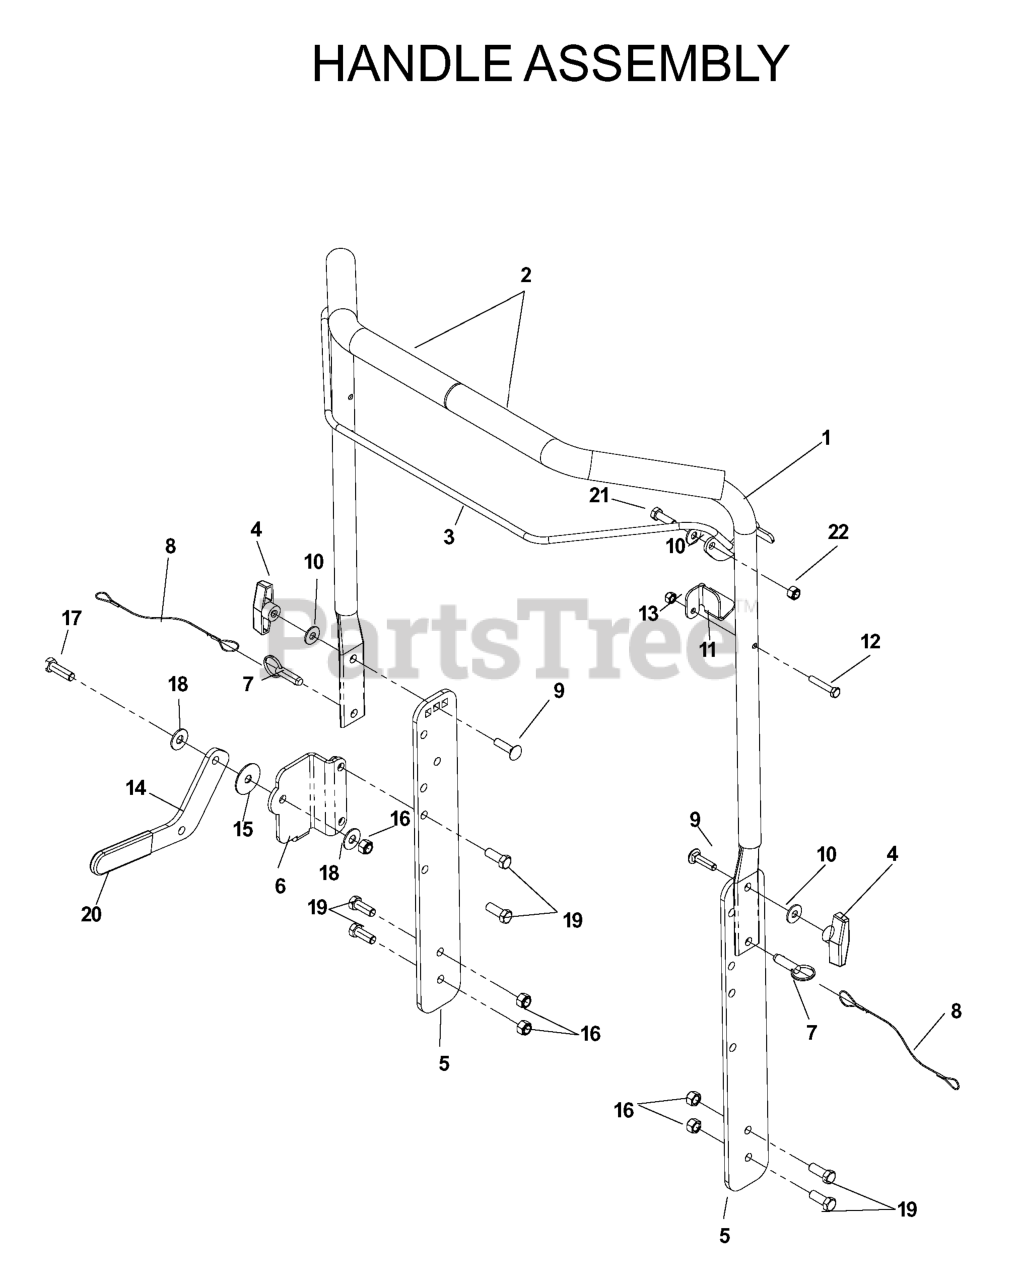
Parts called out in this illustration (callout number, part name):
1	HANDLE GRAY
3	BAIL - ORANGE
5	HANDLE SIDE GRAY
7	DETENT PIN RAKE/DT
9	BOLT, CARRIAGE 5/16X1-1/4
10	WASHER 5/16 FLAT
11	CABLE TAB POWER RAKE
12	SCW 1/4-20 X 1-1/2 HEX
13	NUT.1/4-20.HEX.NYLOC.ZD
15	WASHER, FRICTION
16	NUT 3/8-16 NYLOC
17	HCS 3/8C X 1 1/4 GR5
18	WASHER 3/8 FLAT
19	HCS 3/8-16X1.GRD.5.ZD
21	HCS 5/16C X 1
22	NUT 5/16 NYLOC
